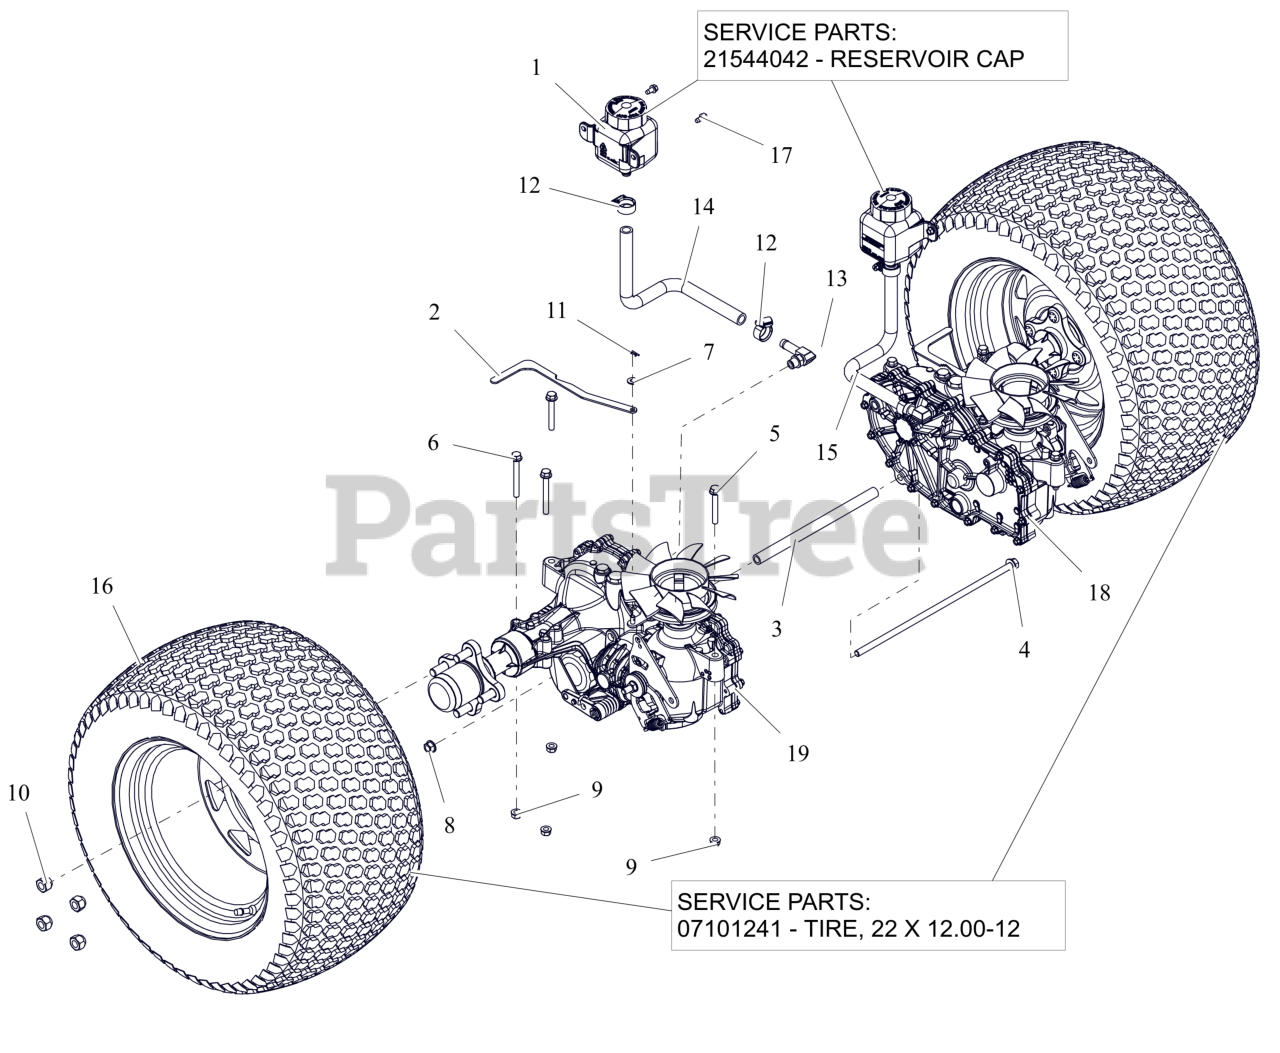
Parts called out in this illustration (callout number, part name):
1	TANK, EXPANSION
1	CAP, HYDRO RESERVOIR REPLAC.
2	BRKT, VALVE DUMP
3	SPCR,TRANS. .406IDX.63ODX9.95L
4	BLT,HEX-FLG .38-16X13 G5 ZCC
5	BLT,HEX-FLG .31-18X2.25 G5 ZCC
6	BLT,HEX-FLG .31-18X2.75 G5 ZCC
7	WSHR,FLT .281X.625X.065 ZCC
8	NUT-LK-TOP-FLG .38-16 ZC120
9	NUT,LK-CTR-FLG .31-18 GF ZCC
10	NUT, WHEEL .50-20 ZCC
11	PIN, HAIR #225 .072X1.09
12	CLAMP,.88 DIA. HOSE
13	FITTING, HYD (90 DEG)
14	HOSE, FORMED EXPANSION -HD RH
15	HOSE, FORMED EXPANSION -HD LH
16	ASM, WHL/TIRE 22X12.00-12 K500
16	TIRE, 22X12.00-12
17	SCR-TAP .25-20X.50 HWH ZCC
18	TRANSAXLE, ZT3100 - LH
19	TRANSAXLE, ZT3100 - RH
